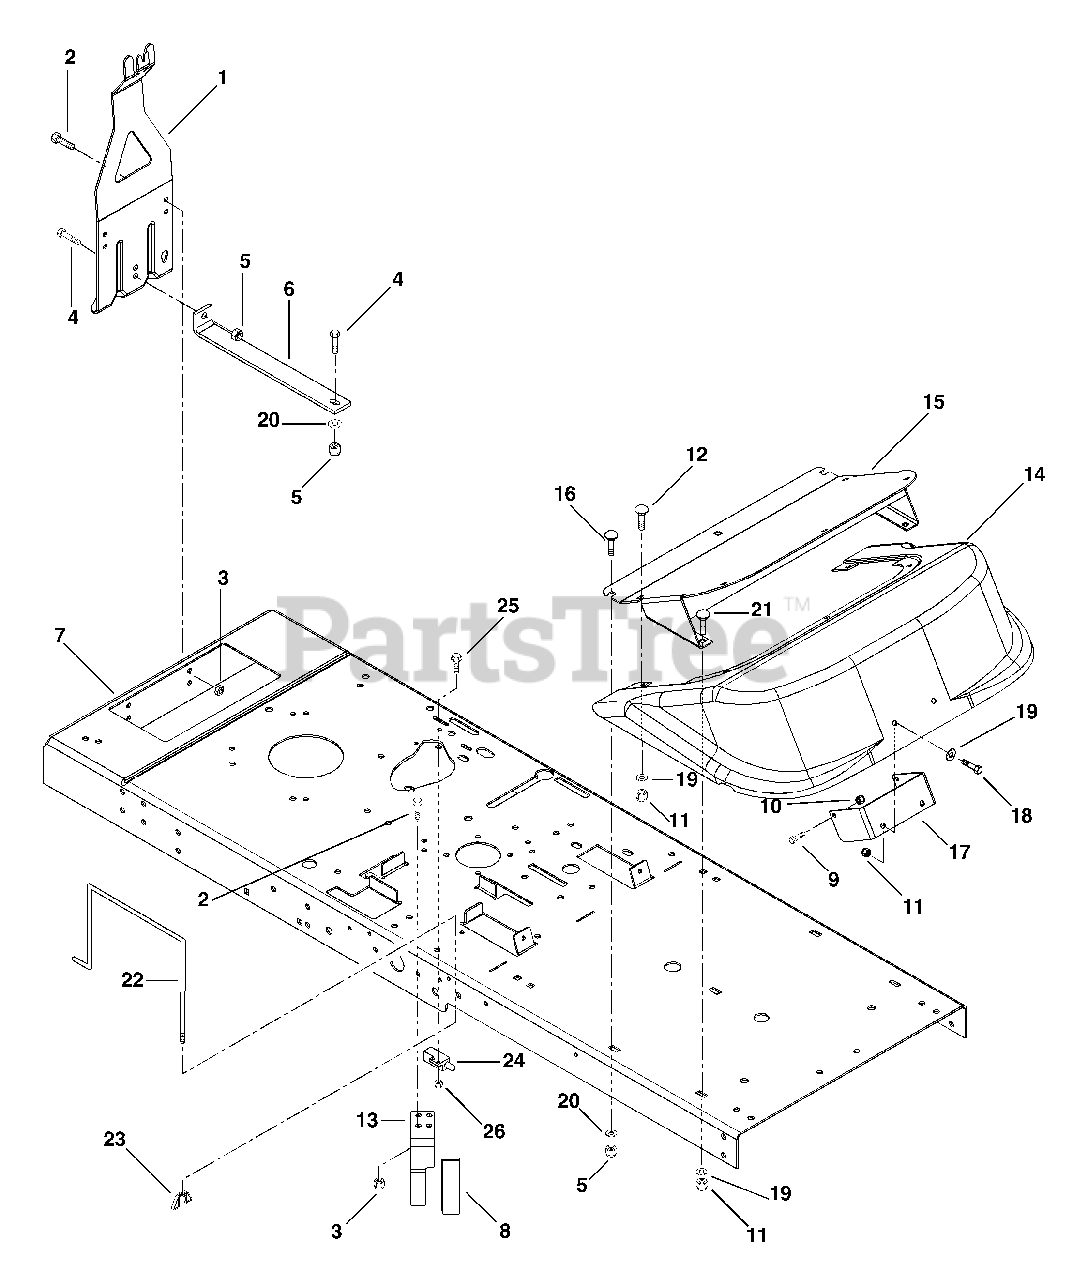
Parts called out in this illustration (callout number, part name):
1	Hitch-Trailer
2	Bolt-Hex .31-18 x .75 Grade 5
3	Nut-Locking-Center .312-18
4	Bolt-Hex .38-16 x 1.00 Grade 5
5	Nut-Locking-Center .38-16
8	Grip
9	Bolt-Hex .25-20 x .75 Grade 5
10	Nut-Locking-Nylon .250-20 Grade 2
11	Nut-Locking-Nylon .312-18 Grade 5
12	Bolt-Round Head Square Short Neck .312-18 x .75 Grade 5
13	Clutch Stop
14	Shroud-Footrest
15	Weldment-Footrest
16	Bolt-Round Head Square Neck .38-16 x .75 Grade 5
17	Bracket-Footrest
18	Bolt-Hex .31-18 x .75 Grade 5
19	Washer-Flat-Steel .375 x .875 x .083
20	Washer-Flat-Steel .406 x .812 x .065
21	Bolt-Round Head Square Neck .312-18 x 1.00 Grade 5
22	Rod-Battery
23	Nut-Locking-Wing .250-20
24	Switch-Single Pole N.O.
25	Bolt-Hex #10-24 Flat Washer Head
26	Nut-Locking-Nylon 10-24 with Insert
